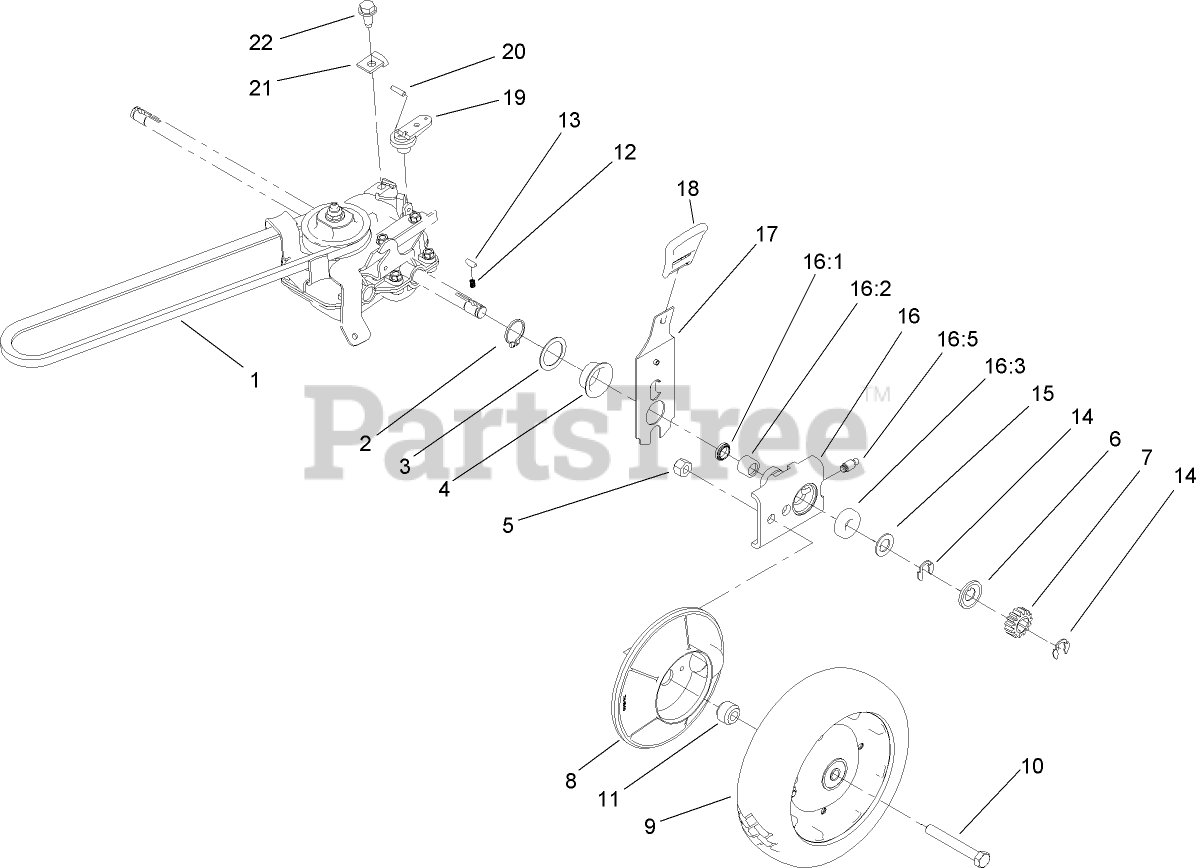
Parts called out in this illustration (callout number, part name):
1	V-BELT
2	RING-RETAINING
3	WASHER
4	CAP-END
5	NUT-LOCK, CONE
6	WASHER-THRUST, OUTER
7	GEAR-PINION
8	COVER-WHEEL
10	SCREW-HH
11	SPACER-COVER, WHEEL
12	SPRING-COMPRESSION
14	RING-RETAINING
15	WASHER-THRUST, OUTER
16	PIVOT ARM ASM
16:1	SEAL-OIL
16:3	BEARING-WHEEL
18	KNOB-HOC
19	LEVER-SHIFT
20	PIN-SPRING
21	CLAMP-CABLE
22	SCREW-HWHTF
